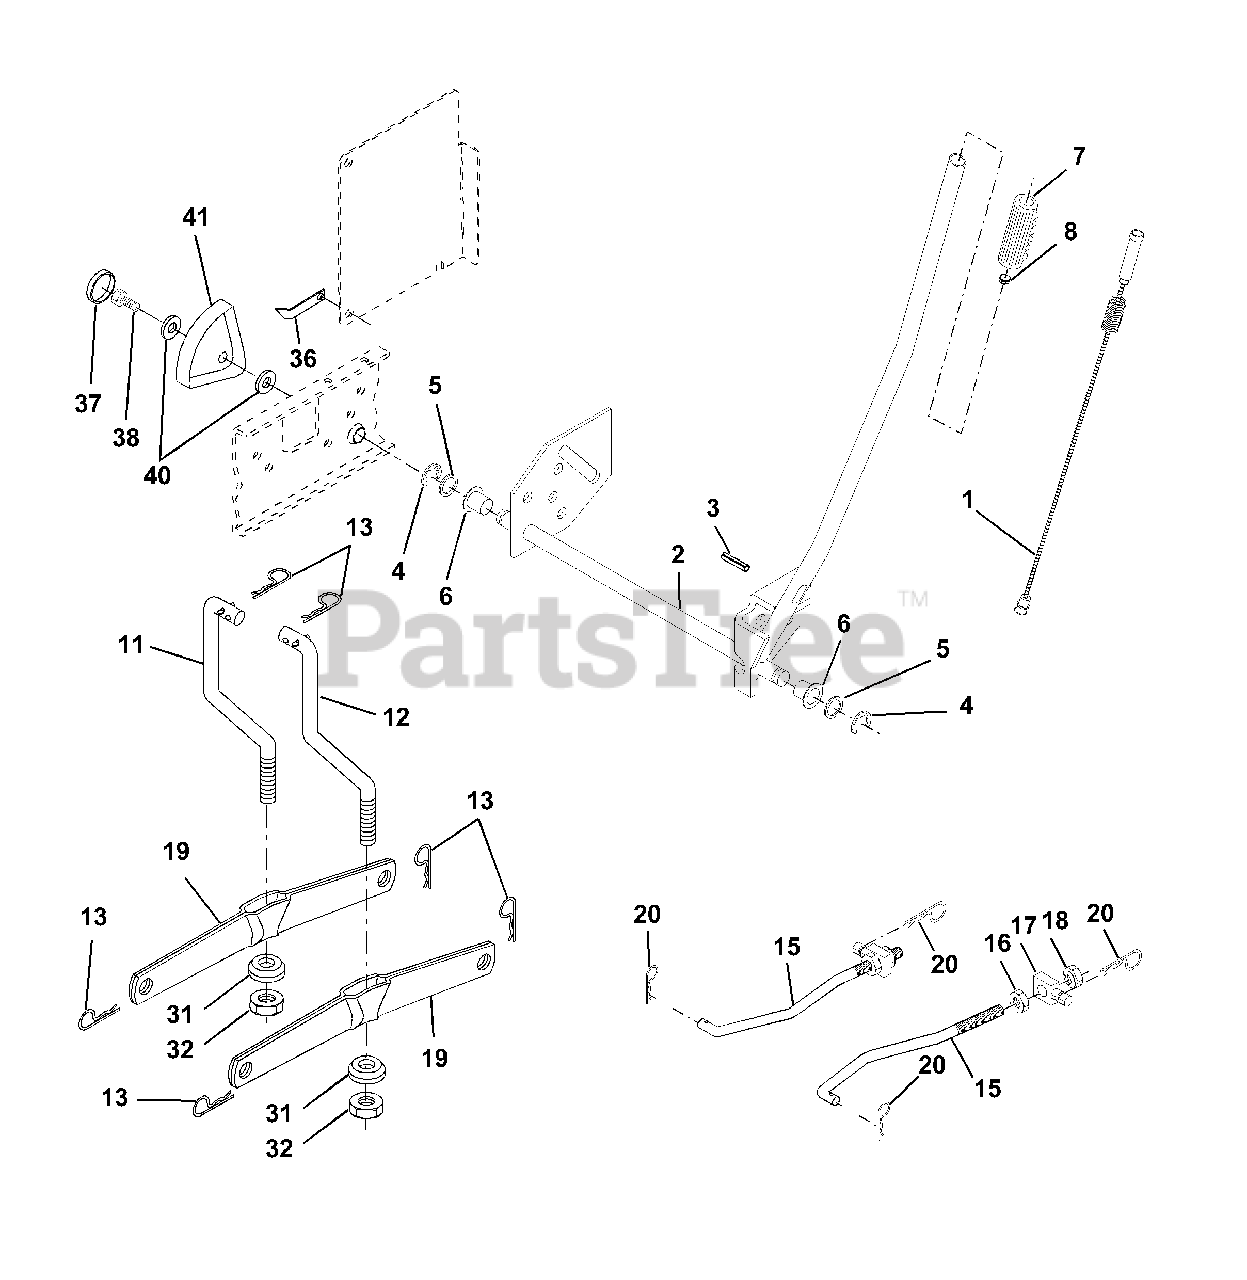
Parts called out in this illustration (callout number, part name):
1	Wire Asm Inner/Sprg W/plunger LT
2	Shaft Asm Lift RH w/Inf
3	Pin Groove 1 500 Zinc
4	E Ring #5133-62
5	Washer 21/32 X 1 X 21 Ga
6	Bearing Nylon Blk 629 Id
7	Grip Handle
8	Button Plunger
11	Link Lift LH Fixed Length
12	Link Lift RH Fixed Length
13	Retainer Spring
15	Link Front
16	Nut Jam Hex 1/2-13 Unc
17	Trunnion Blk Zinc
18	Nut Lock W/Wsh 1/2-13 Unc
19	Arm Suspension Rear
20	Retainer Spring
31	Bearing Pvt Lift
32	Nut Crownlock 3/8 - 24
36	Pointer Height Indicator
37	Plug Hole Blk. 1.485/1.515 Dia.
38	Screw 5/16-18 x 1
40	Washer 11/32 x 1-1/210 Ga.
41	Indicator Height STLT
